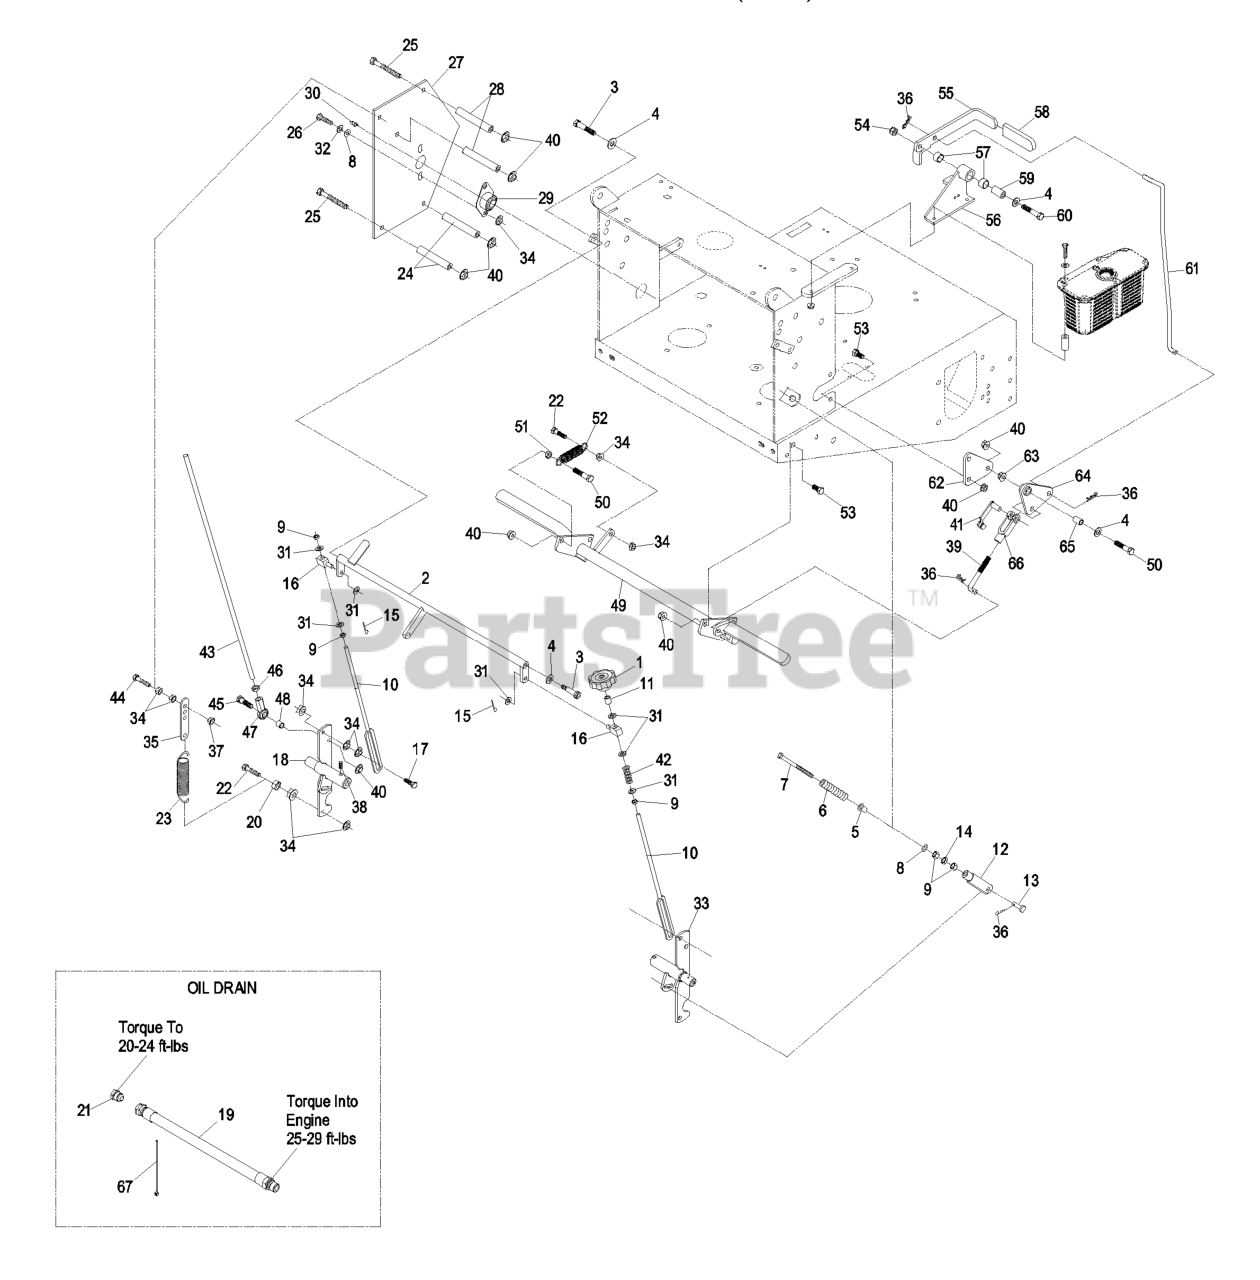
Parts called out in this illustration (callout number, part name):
1	KNOB-TRACKING
2	CRANK-CONTROL, SPEED
3	SCREW-HSH
4	WASHER-FLAT
5	BUSHING-FLANGED
6	SPRING,COMPRESSION (NEUT)
7	BOLT-RETURN, NEUTRAL
8	WASHER-FLAT
9	NUT-HEX
10	LINK-CONTROL, SPEED
12	YOKE-ADJUSTABLE
13	PIN-CLEVIS
14	NUT-JAM
15	PIN-COTTER
17	SCREW-HH
18	SHAFT-CONTROL, LH
20	NUT-JAM
22	SCREW-HH
23	SPRING-EXTENSION
24	SPACER-SHIELD
25	SCREW-HH
26	SCREW-HH
27	SHIELD-CONTROL
28	SPACER-SHIELD
29	BEARING-FLANGE, SIDE
30	FITTING-GREASE
31	WASHER-PLAIN
32	WASHER-LOCK
33	SHAFT-CONTROL, RH
35	TAB-SPRING, EXTENSION
36	PIN-COTTER
37	NUT-LOCK, NI
38	SCREW-SET
39	LINKAGE-LOWER
40	NUT-HHF, WHIZ
41	PIN-SPRING, CLEVIS
42	SPRING-COMPRESSION
43	LINKAGE,DRIVE (PLT)
44	BOLT-TAP, HH
45	SCREW-HH
46	NUT-HEX JAM, LH
47	JOINT-BALL END, LH
48	SPACER-TUBE, PUMP LINK
50	SCREW-HH
51	NUT-JAM
52	SPRING-IDLER
53	SCREW-HH
54	NUT-LOCK, NI
55	LEVER,PARK BRK W/DECAL
56	BRACKET ASM
57	SLEEVE-BUSHING
58	GRIP-LEVER
59	BUSHING-PIVOT
60	SCREW-HH
61	LINKAGE-UPPER
62	BELLCRANK
64	BELLCRANK ASM
65	BUSHING-PLASTIC
66	YOKE-LINKAGE, BRAKE
67	TIE-CABLE
